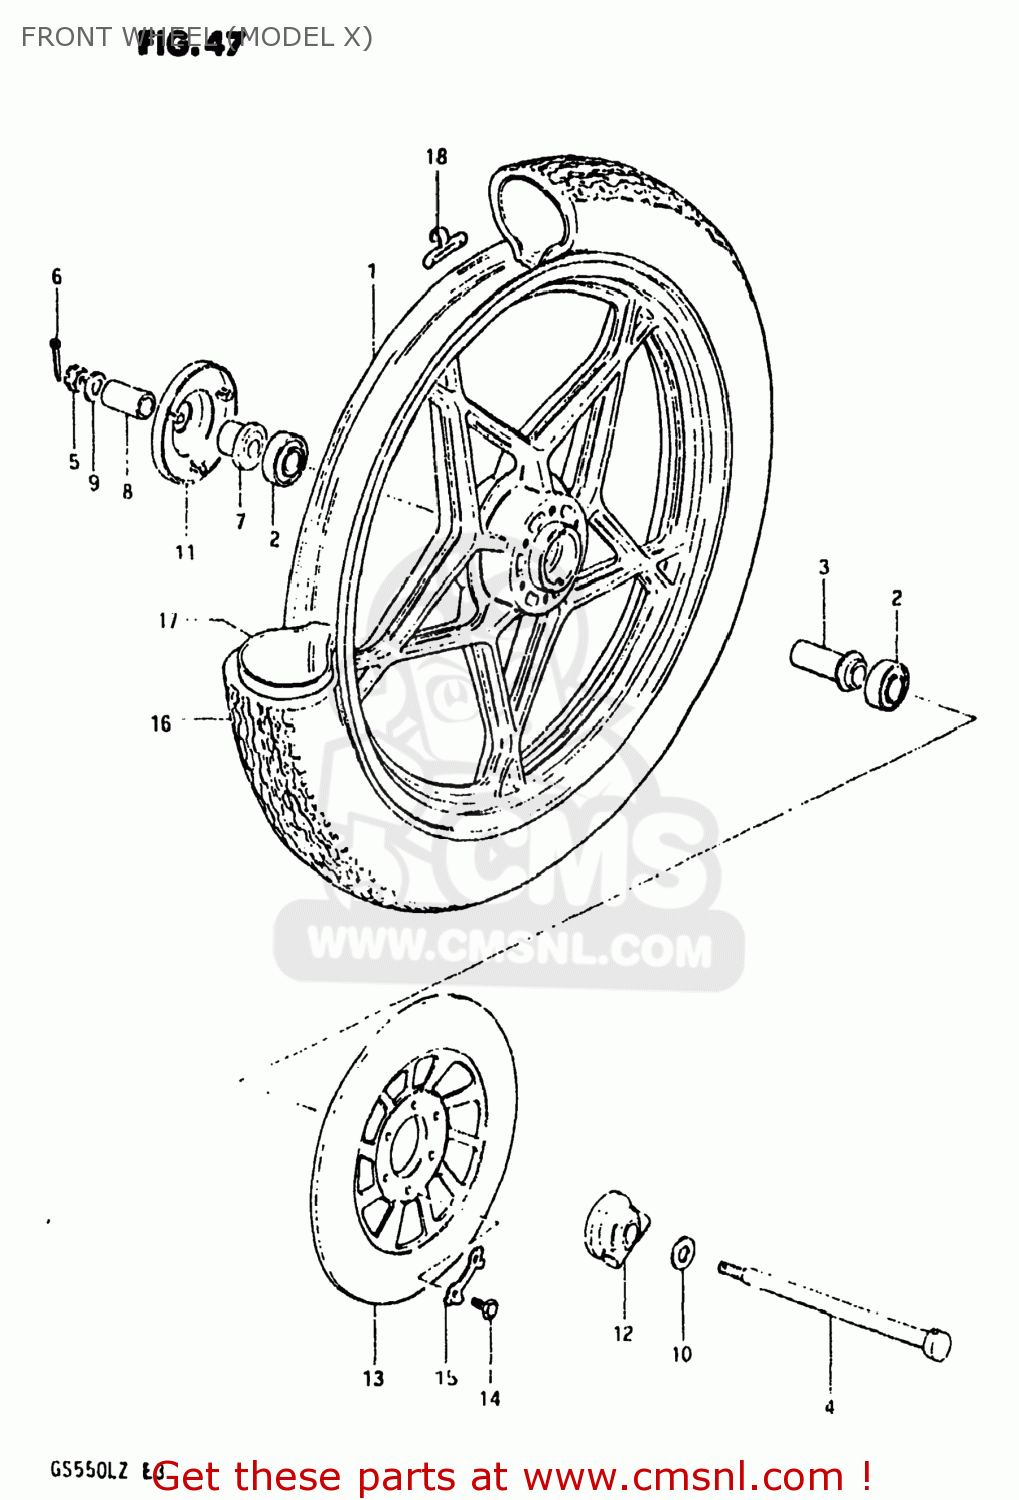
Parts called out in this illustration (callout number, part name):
1	WHEEL (1.9X1.85)
2	BEARING
3	SPACER,FR HUB BEARING
4	AXLE,FR
5	NUT 12MM
6	COTTER PIN
7	SPACER,FR AXLE,R
8	SPACER
9	WASHER
10	WASHER(15.5X26X2.3)
11	COVER,FR HUB,R
12	BOX ASSEMBLY,SPEEDOMETER GEAR
13	DISC,BRAKE
14	BOLT(8X25)
15	WASHER
16	TIRE,FRONT
17	TUBE 2.75-19 070-483MM
18	BALANCER,WHEEL
